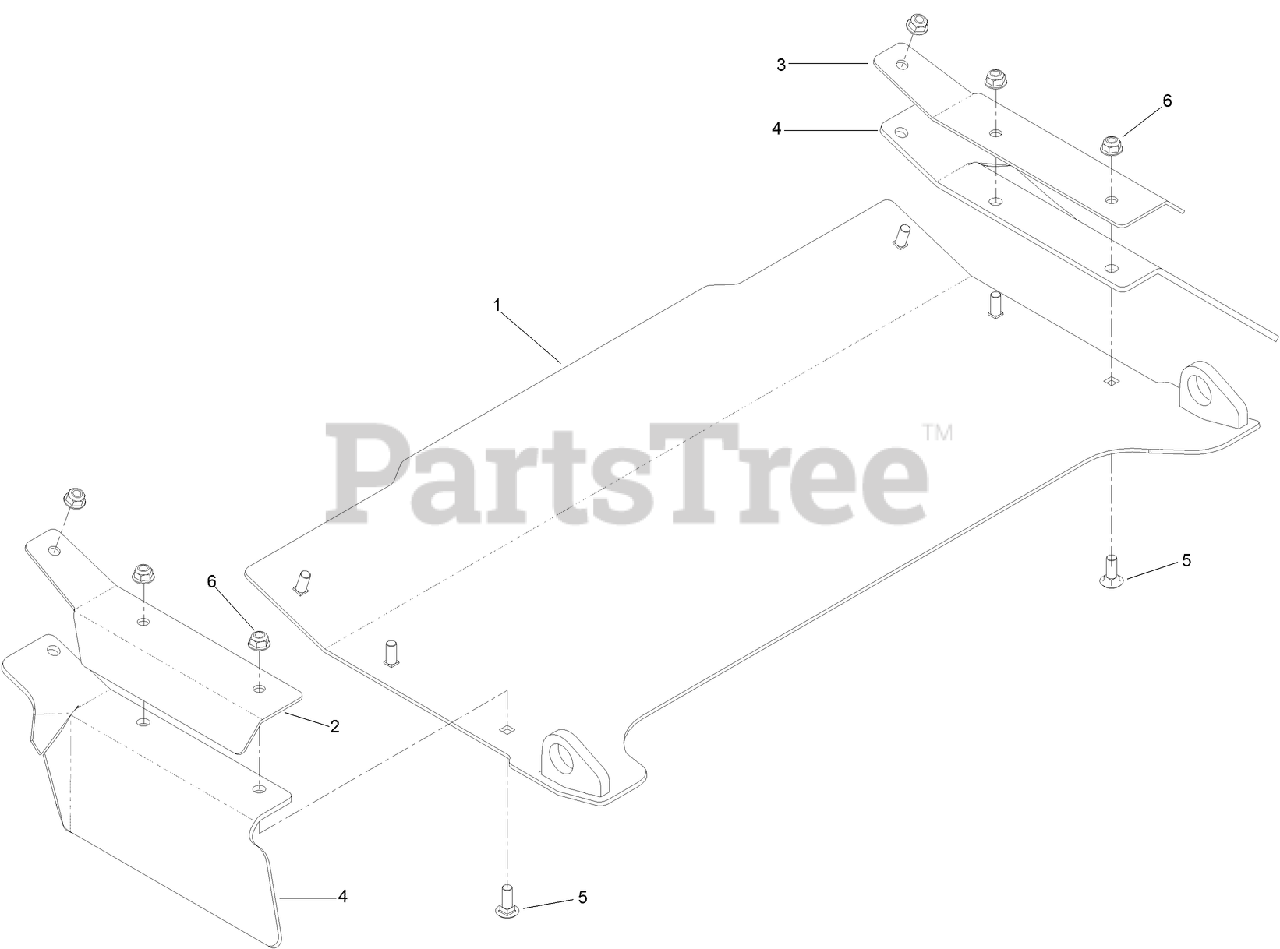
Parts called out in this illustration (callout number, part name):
1	DISCHARGE TUNNEL ASM
2	BRACKET-FLAP, LH
3	BRACKET-FLAP, RH
4	FLAP-RUBBER
5	SCREW-CARR
6	NUT-HF, NI
